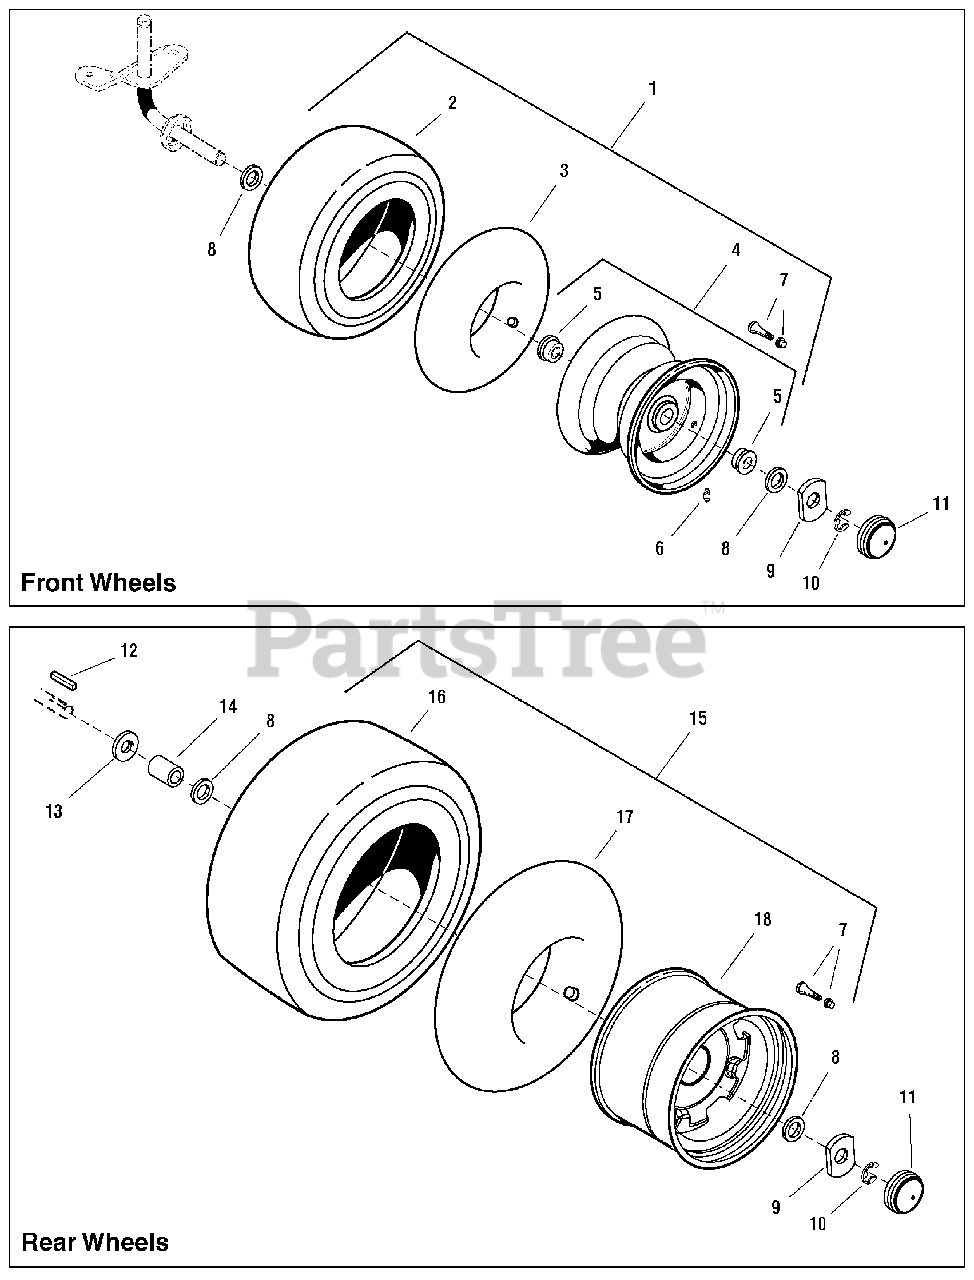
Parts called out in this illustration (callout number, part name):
1	WHEEL & TIRE ASSEMBLY, Front
2	TIRE, Turf 15 X 6.00 - 6 Saver TL
3	TUBE, Tire, Front
4	WHEEL & BUSHINGS ASSEMBLY, Front
5	BEARING
6	FITTING, Grease, 1/4-28 Thread
7	VALVE STEM & CAP
8	WASHER, 3/4
9	WASHER, Special Yellow
10	RING, Retaining
12	KEY, 3/16 x 3/16 x 3
14	SPACER, 0.77 ID x 1-1/4 OD x 1.65 LG Powdered Metal Black
15	WHEEL & TIRE ASSEMBLY, Rear 22"
16	TIRE, Turf 22 X 10.00 - 8 Saver TL
17	TUBE, Tire, Rear, 22 X 10 - 8
18	WHEEL, Hub
